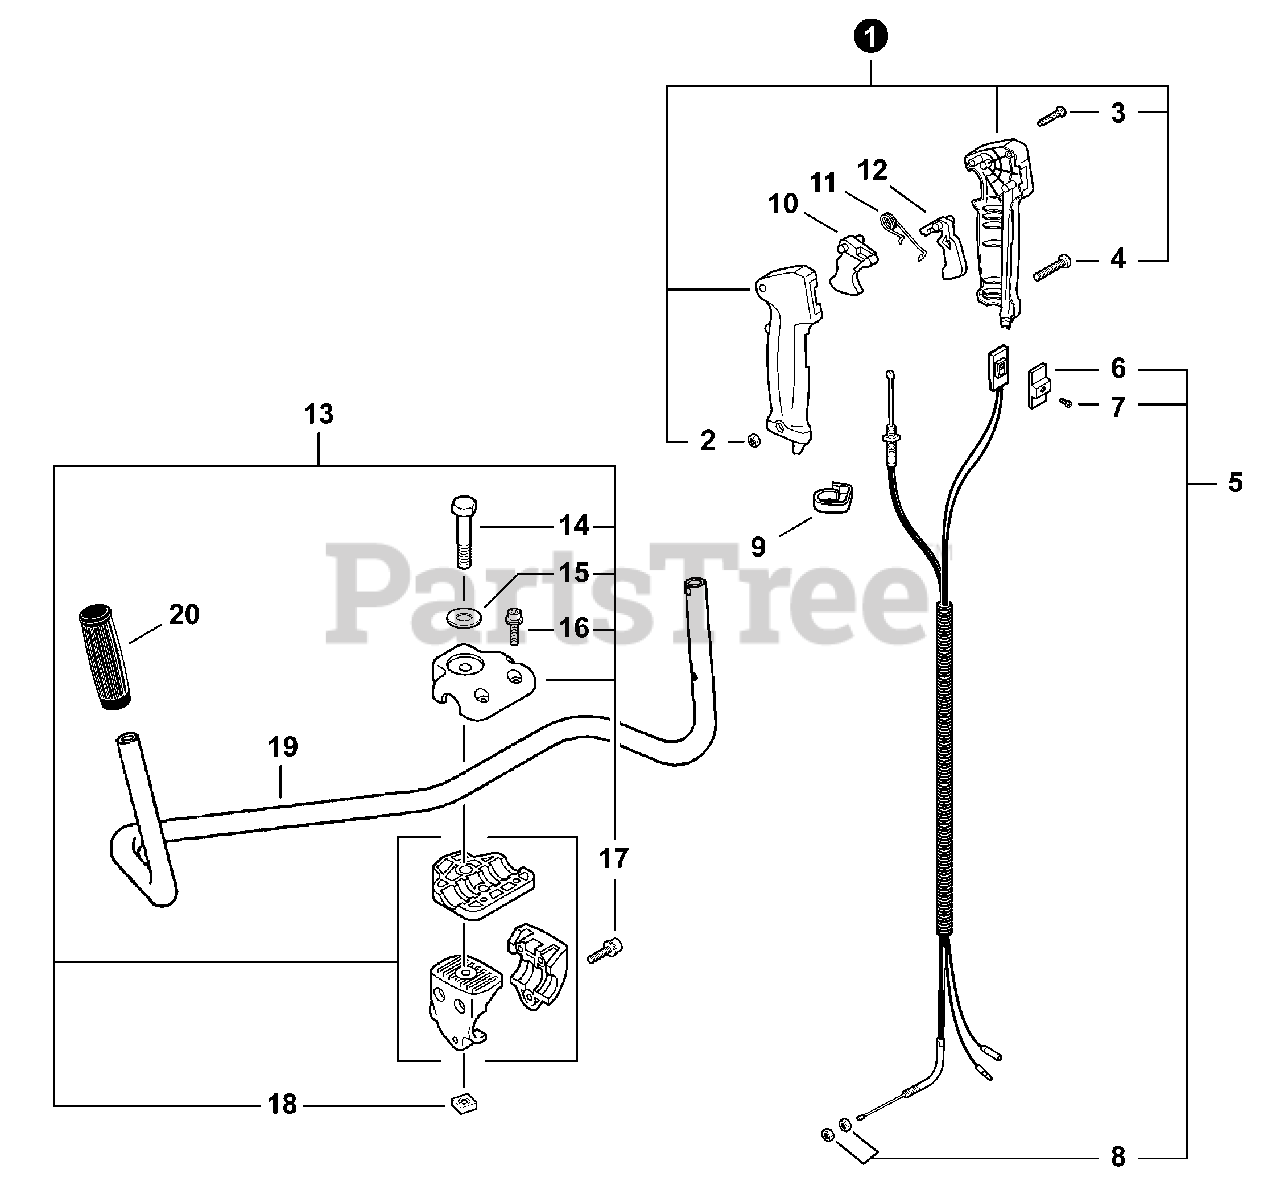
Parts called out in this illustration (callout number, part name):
1	THROTTLE CONTROL ASY
3	SCREW - 3X25
4	SCREW - 5X30
5	CONTROL CABLE ASY
7	SCREW - 3X10
8	LOCKNUT - 6
10	TRIGGER, THROTTLE
11	SPRING, THROTTLE LOCK
12	LOCKOUT, TRIGGER
13	HANDLE BRACKET KIT
16	SCREW - 5X20
17	SCREW - 5X30
19	HANDLE - FRONT
20	GRIP, HANDLE - LEFT
